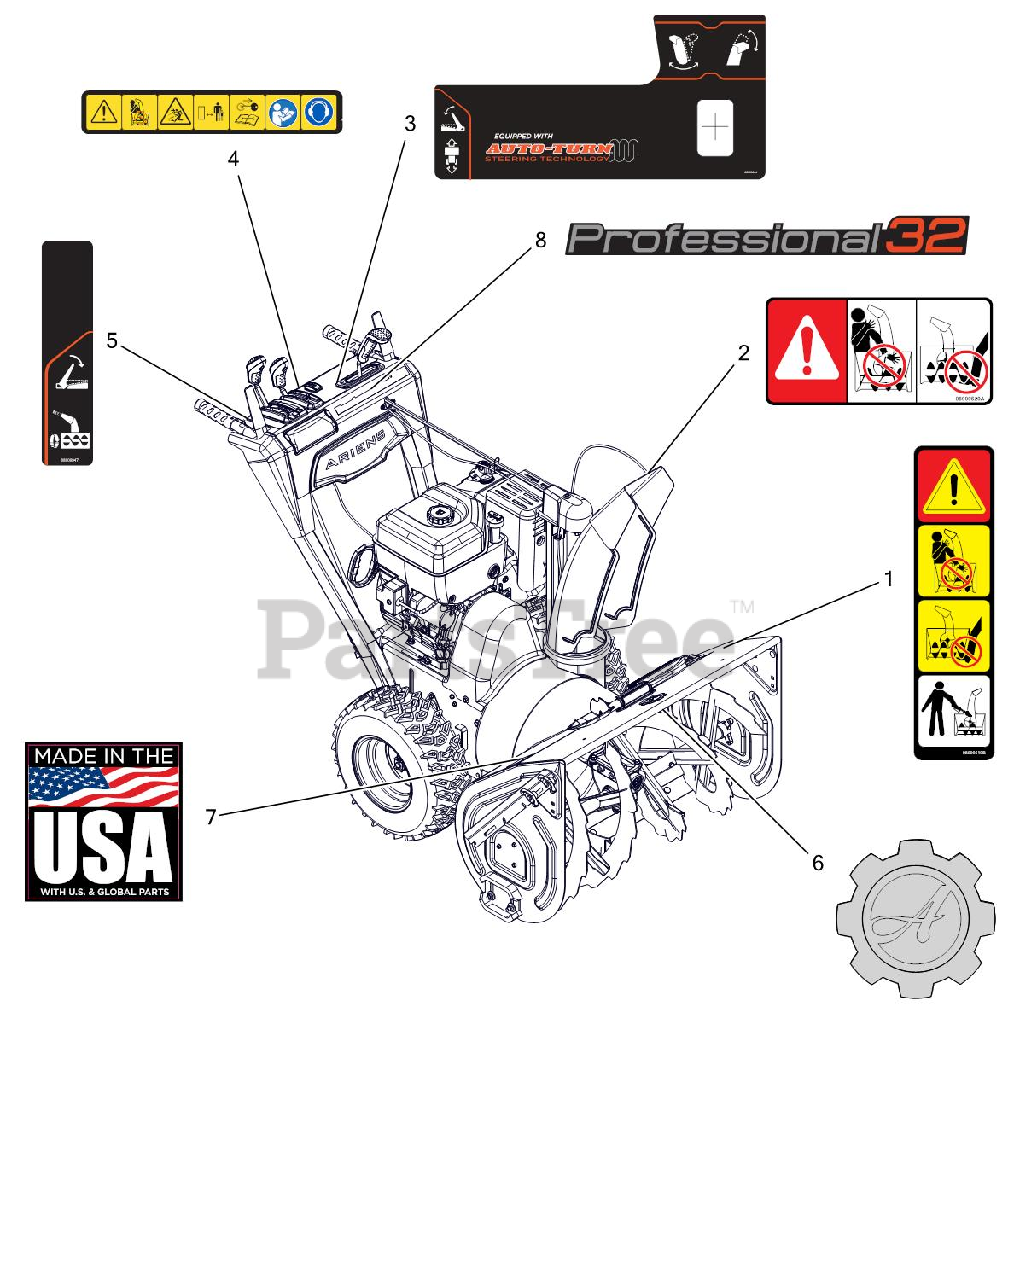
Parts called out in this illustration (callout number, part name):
1	DECAL, DANGER - ROTATING PARTS
2	DECAL, DANGER
3	DECAL,CONTROL-LG QT2
4	DECAL,DASH - SAFETY
5	DECAL,CONTROL-RH CONTROL
6	DECAL, ARIENS-GEAR BADGE
7	DECAL, MADE IN USA
8	DECAL, DASH - PRO 32
